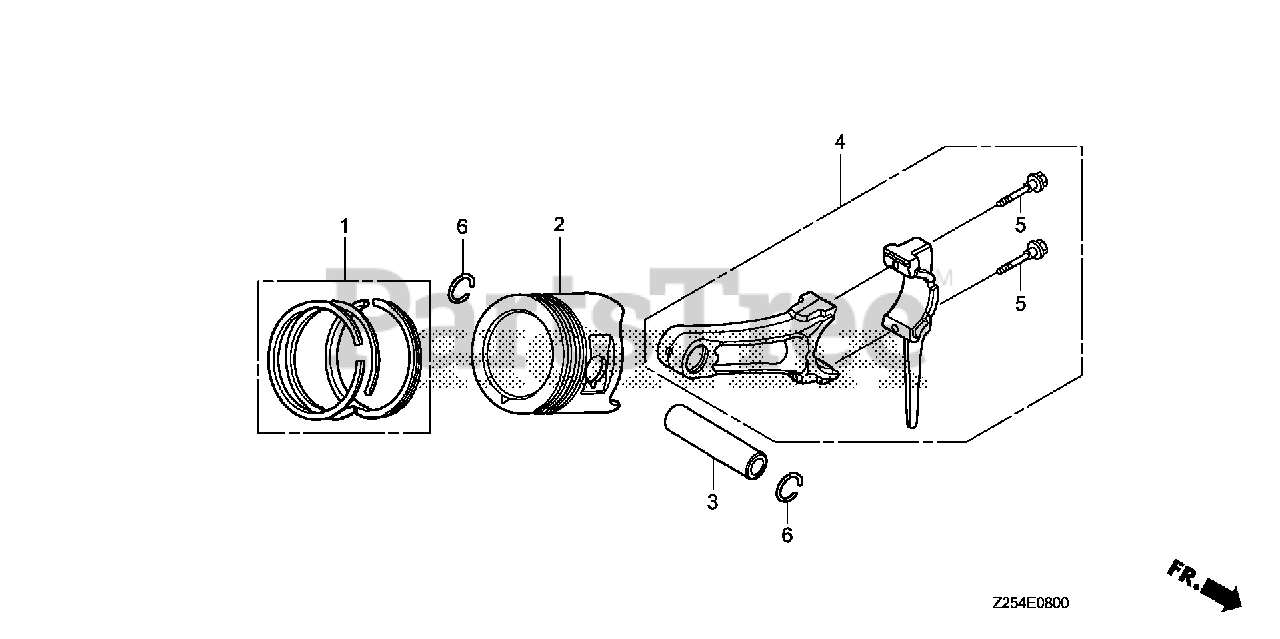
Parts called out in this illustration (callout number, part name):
1	RING SET, PISTON (STD)
1	RING SET, PISTON (STD) (TEIKOKU)
1	RING SET, PISTON (OS 0.25)
1	RING SET, PISTON (0.25) (TEIKOKU)
1	RING SET, PISTON (OS 0.50)
1	RING SET, PISTON (0.50) (TEIKOKU)
1	RING SET, PISTON (0.75) (NIPPON)
1	RING SET, PISTON (0.75) (TEIKOKU)
2	PISTON (STD)
2	PISTON (OS 0.25)
2	PISTON (0.25)
2	PISTON (OS 0.50)
2	PISTON (0.50)
2	PISTON (OS 0.75)
2	PISTON (0.75)
3	PIN, PISTON
4	ROD ASSY., CONNECTING (US 0.25)
4	ROD ASSY., CONNECTING (STD)
5	BOLT, CONNECTING ROD
6	CLIP, PISTON PIN (20MM)
